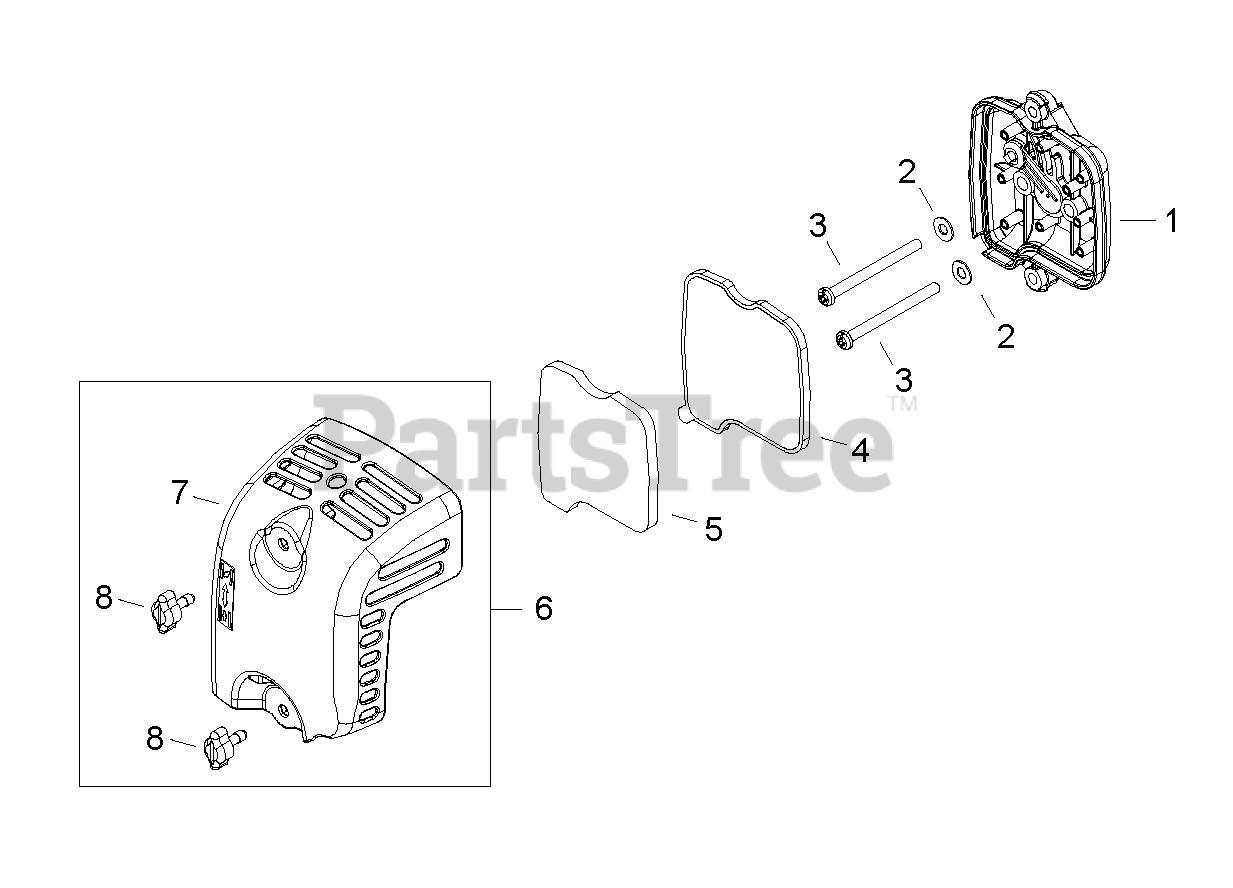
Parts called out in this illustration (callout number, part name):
1	AIR FILTER CASE ASSY
2	WASHER - 5
3	SCREW - 5X60
4	FILTER, AIR
5	PRE-FILTER - FOAM
6	AIR FILTER COVER ASSY
7	COVER, AIR FILTER
8	THUMBSCREW
